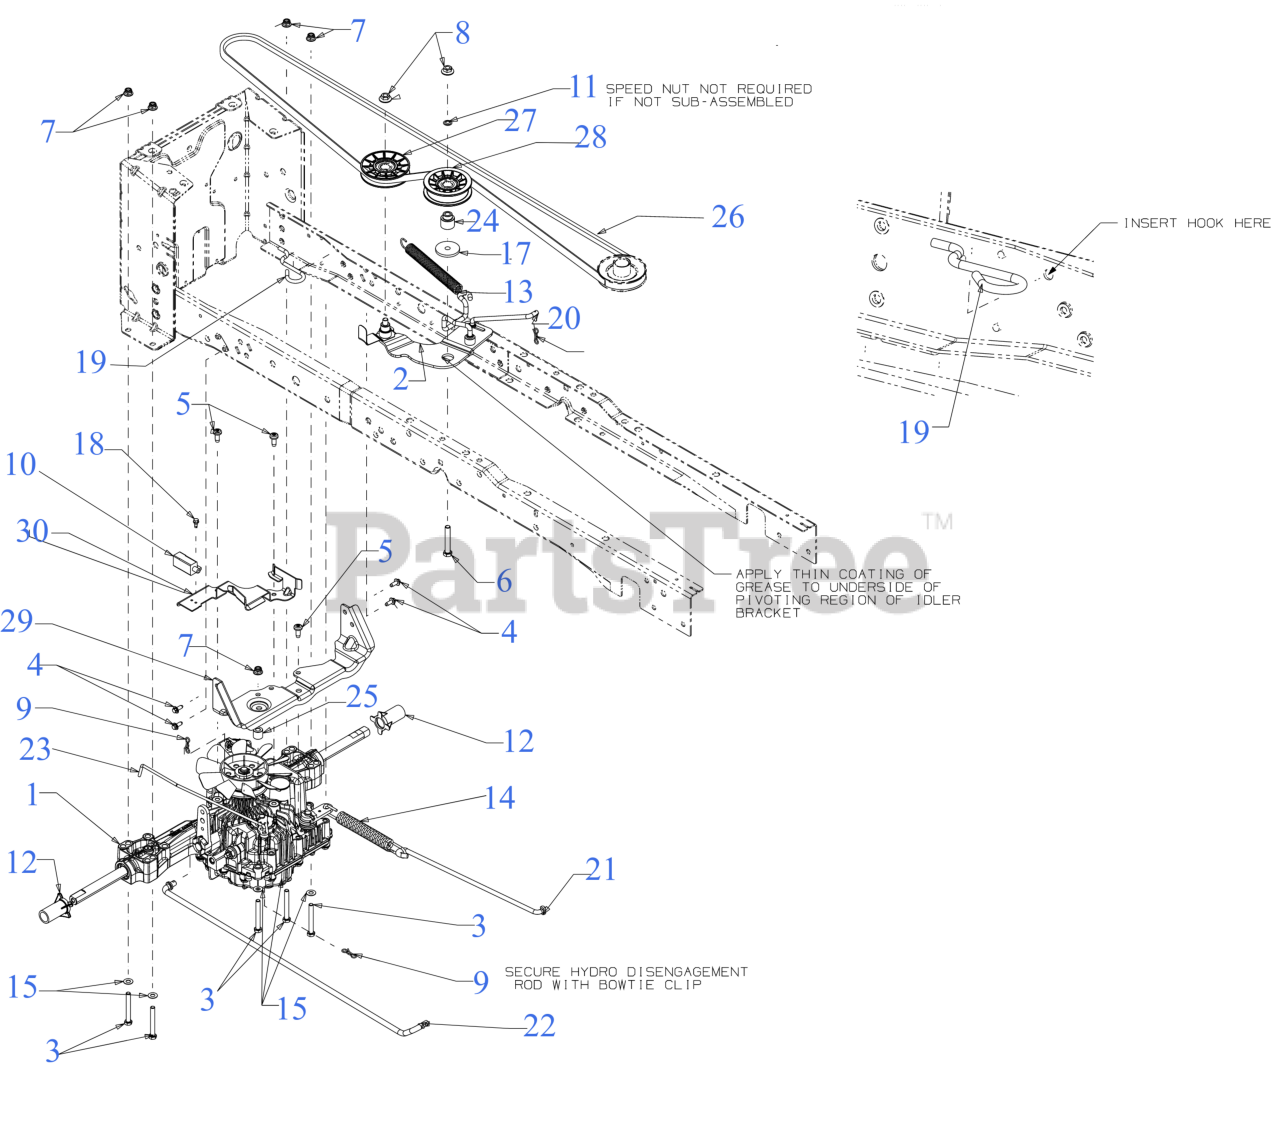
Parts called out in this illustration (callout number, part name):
1	TRANSMISSION ASSEMBLY
2	IDLER BRACKET ASSEMBLY
3	SCREW 5/16-18 x 2.5 GR 5
4	SCREW M6-1 x .625
5	SCREW 5/16-18 x .750
6	SCREW 3/8-16 x 2.25 GR5
7	FLANGE LOCK NUT 5/16-18
8	FLANGE LOCK NUT
9	BOW TIE COTTER PIN 1/4-5/16
10	INTERLOCK SWITCH (NO/NC)
11	PUSH NUT
12	AXLE SLEEVE .765 ID x 2.11 LG
13	EXTENSION SPRING .790 DIA x 8.41
14	EXTENSION SPRING 0.90 DIA x 8.14
15	FLAT WASHER
17	SHOULDER SPACER
18	SHOULDER SCREW
19	DECK SPRING HOOK
20	IDLER BRACKET ROD
21	BRAKE ROD
22	HYDRO CONTROL ROD
23	HYDRO DISENGAGEMENT ROD
24	SHOULDER SPACER
25	SPACER .34 x .75 x .63 LG
26	V-BELT A SEC x 90.90
27	V-IDLER PULLEY 3.56 OD
28	FLAT IDLER PULLEY 3.00 OD
29	TRANSMISSION MOUNTING BRACKET
